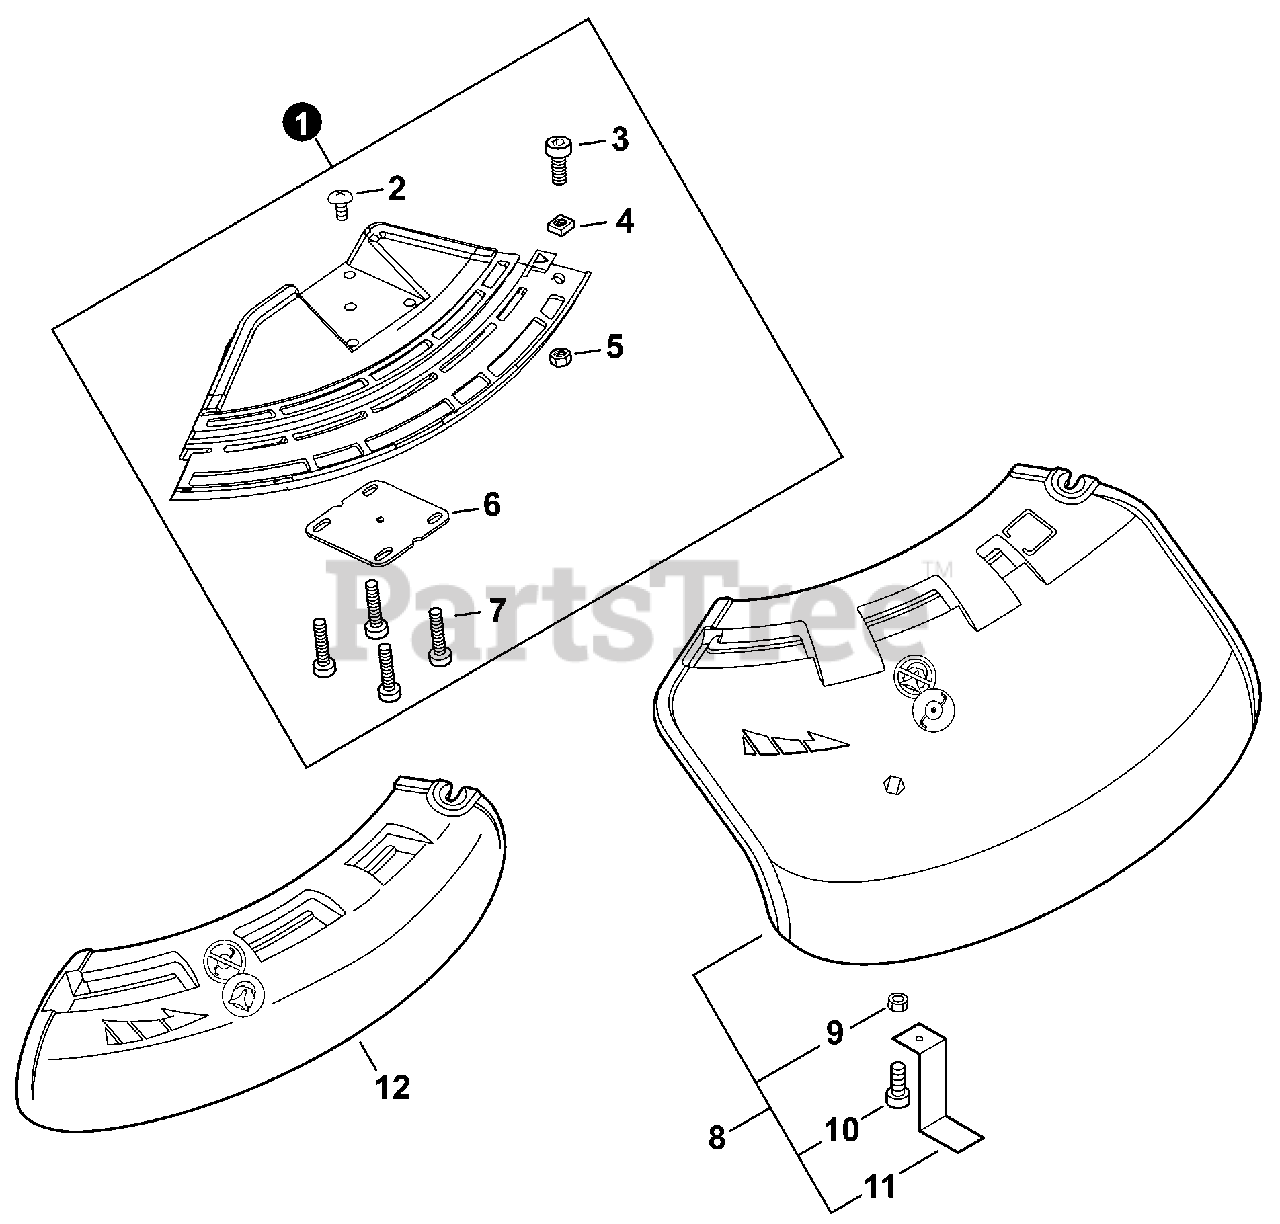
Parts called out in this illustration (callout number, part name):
1	DEBRIS SHIELD BASE ASSY
3	BOLT, TORX 5x25
4	NUT M5
5	NUT, LOCK M5
6	PLATE, SHIELD
7	BOLT, TORX 5x25
8	DEBRIS SHIELD ASSY - TRIMMER EXTENSION
10	BOLT, TORX 5x16
12	SHIELD, BLADE
